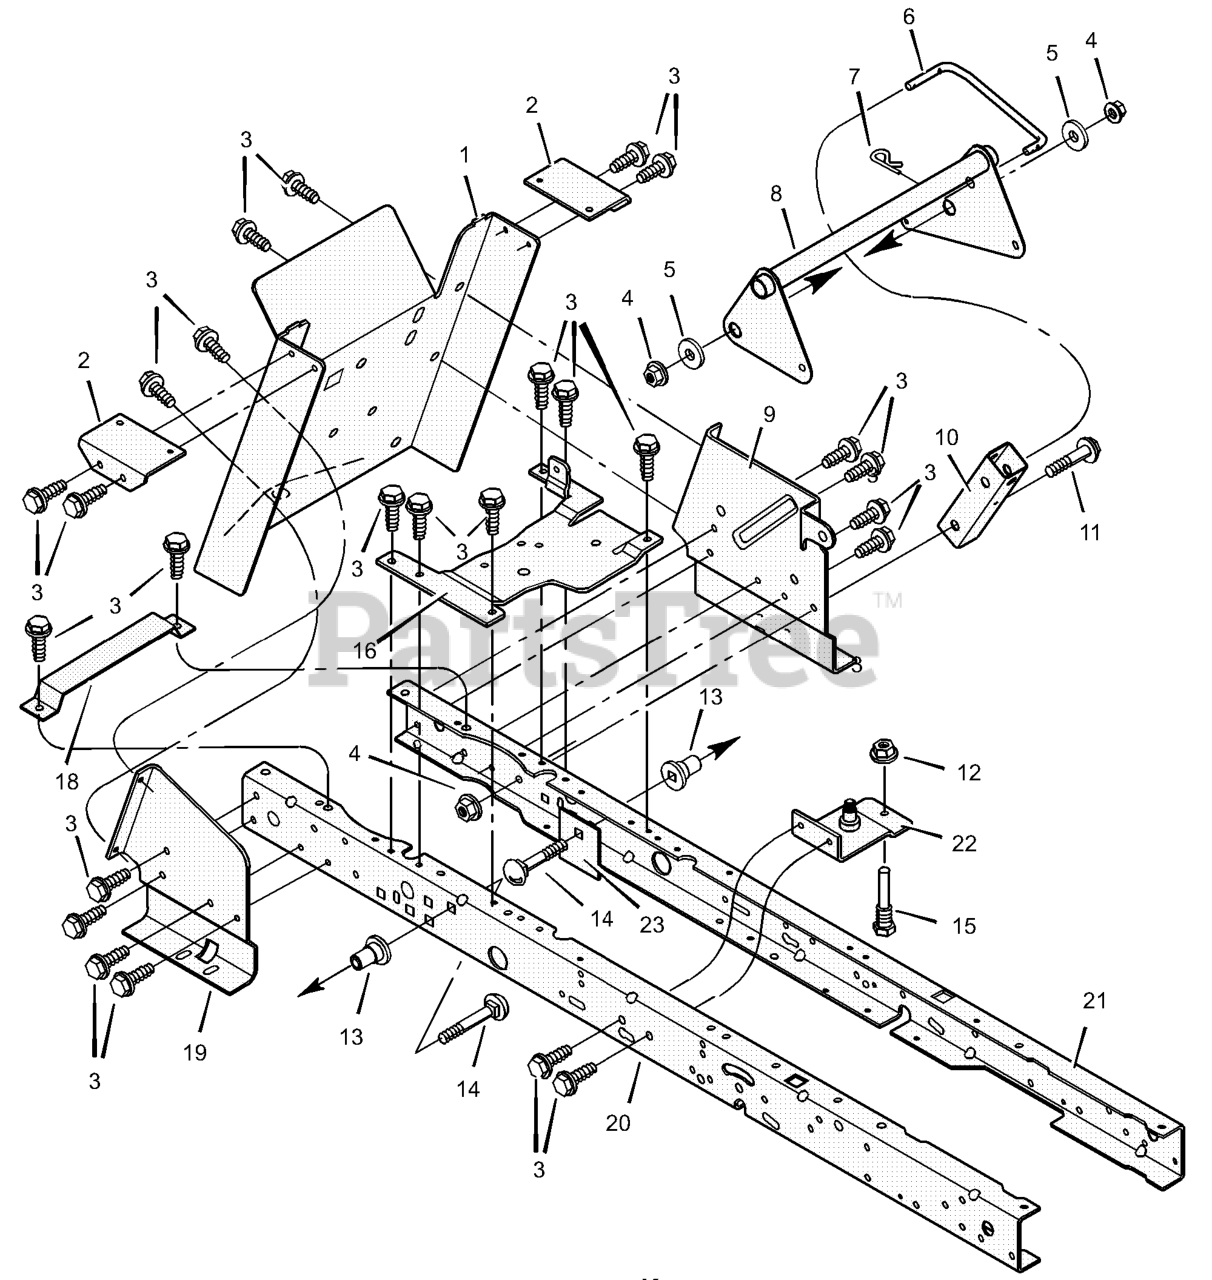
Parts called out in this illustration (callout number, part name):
1	Frame, Rear Hitch
2	Bracket, Seat Deck
4	Nut, Flange
6	Link, Lift Handle
7	Pin, Hair
8	Assembly, Lifter
9	Bracket, Left Transaxle
10	Bracket, Lift Pivot
11	Bolt, Shoulder
12	Nut
13	Spacer, Lifter
14	Bolt, Carriage
15	Guide, Belt
16	Bracket, Stationary Idler
19	Bracket, Right Transaxle
20	Frame, Right
21	Frame, Left
22	Bracket, Idler
23	Plate, Stiffening
